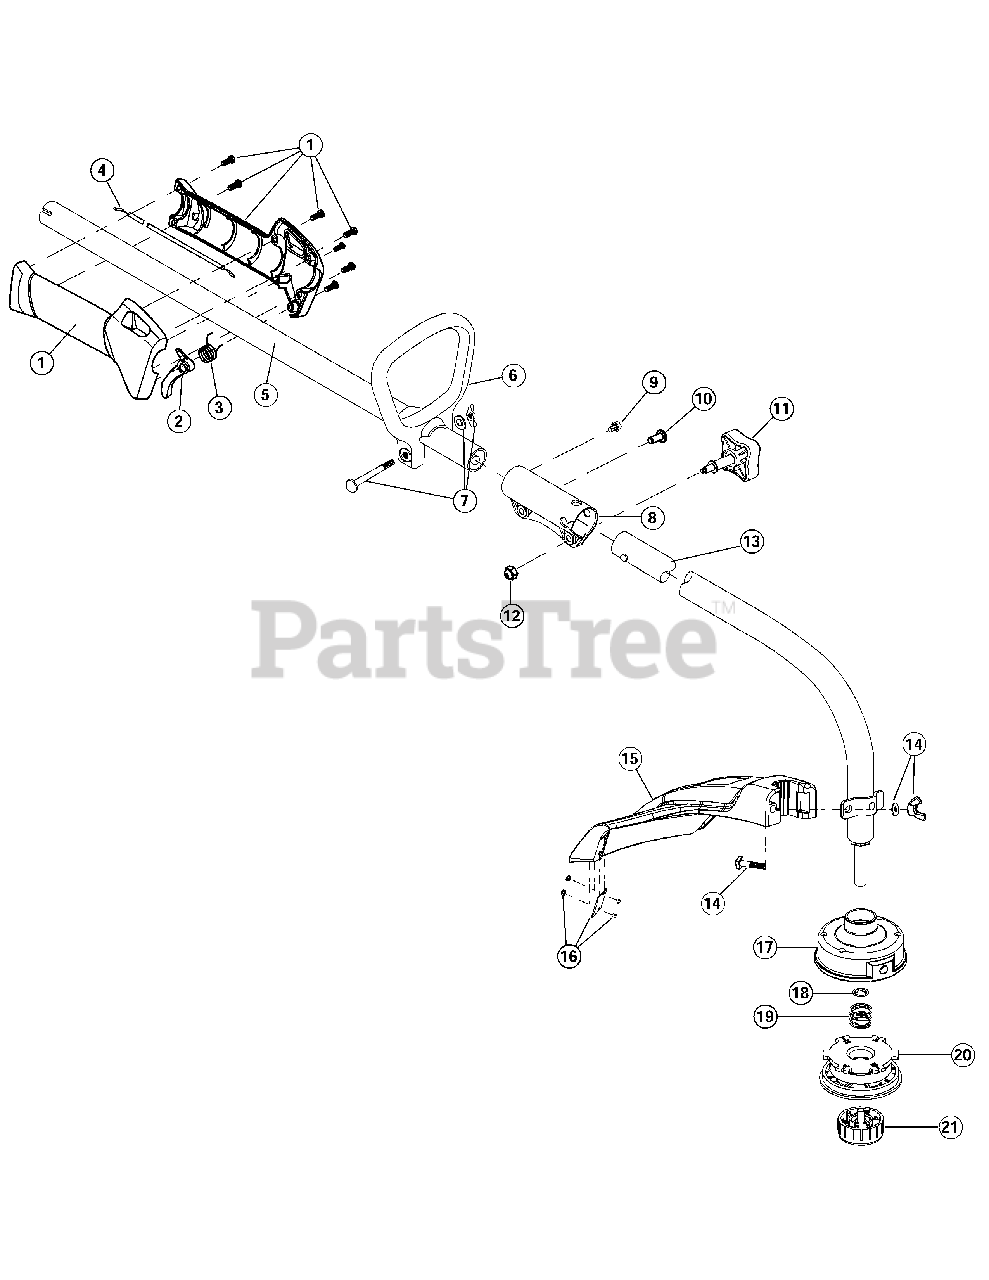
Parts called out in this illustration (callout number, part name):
1	Throttle Housing Assembly (includes 2 & 3)
2	Throttle Trigger
3	Throttle Trigger Spring
4	Throttle Cable
5	Upper Drive Shaft Housing Assembly
6	D-Handle (includes 7)
7	Handle Hardware
8	Split Boom Coupler (includes 9-12)
11	Adjustment Knob
12	Knob Retaining Nut
13	Lower Drive Shaft Housing Assembly
14	Guard Mounting Hardware
15	Guard (includes 16)
16	Blade Assembly
17	Outer Spool Assembly (includes 18)
20	Inner Reel
21	Bump Head Knob Assembly
